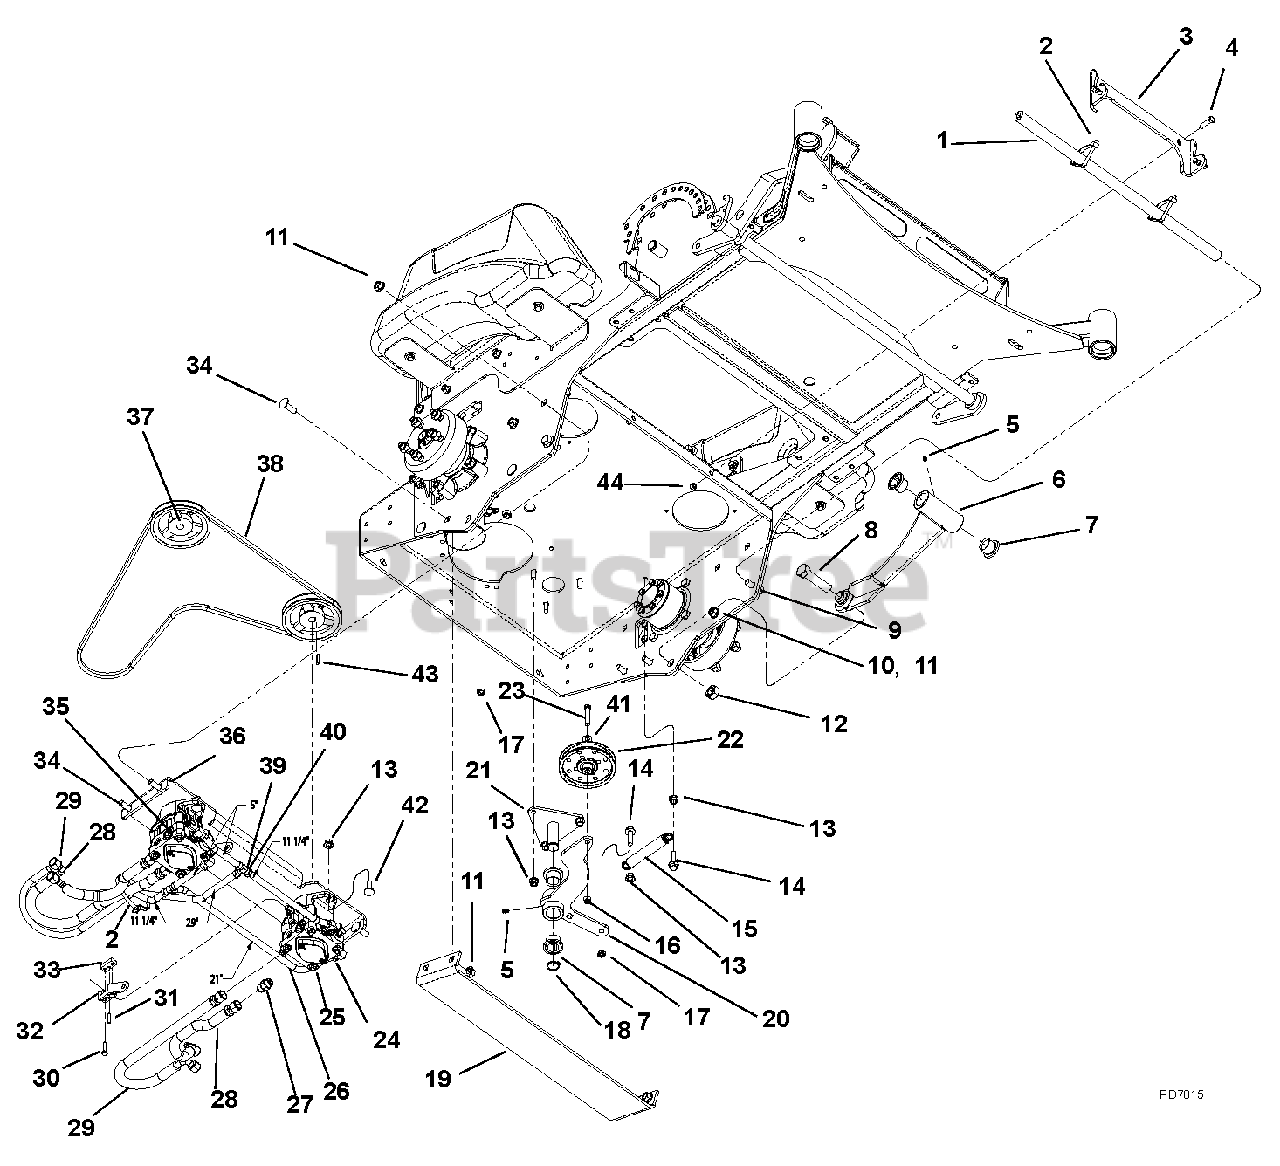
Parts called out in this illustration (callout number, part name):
1	BAR, TIE
2	CABLE TIE, .31 X 14.6 -BLACK
3	WLDT, DAMPNER BRACKET
4	SCREW, HEX FLANGE HEAD
5	FTG, 1/4-28 STRGT GREASE ZERK
6	WLDT, LH THRUST ARM
7	BRG, FLG 1.00 X 1.25 X 1.00
8	SCREW, HEX HEAD 3/4-16X3.00 Y
9	SCREW, FL, JDS123, M14 X 2.0 X 30-10.
10	BOLT, RD HD SQNECK JDS137M 12 X 1.
11	LOCKNUT, M12 X 1.75 DFLCTFLG 10Y
12	LOCKNUT, 3/4-16 CROWN C
12	2
13	LOCKNUT, FL, ISO7044, M10-1.50
14	SCREW, HEX, FL, JDS121, M10 X 1.5 X 40
15	SPRING, EXT .900 X .135 X 4.50 Y
16	NUT, 3/8-16 PTHN
16	1
17	NUT, JDS182, M10 X 1.5-04-ZN
18	RING, SNAP
19	PLATE, SUPPORT
20	WLDT, ARM IDLER
21	PIVOT, IDLER MOUNTING, WELDMENT
22	PULLEY, FLAT 4.50 X .375 W/BRG
23	BOLT, 3/8 X 2.00 A17D ZINC HEX
24	FTG, 90 9/16 MOR X 3/8 HOSE
25	PUMP, HYDRO BDP-10A-101
26	HOSE, 3/8 SAE30R7 FUEL & OIL
27	FITTING, STRAIGHT
30	SCREW, HEX HEAD 1/4-28 X 1 1/4
31	PIN, SPRING M5X30 Y
32	WLDT, LH PUMP ARM
33	PLATE, PUMP A'TCH
34	BOLT, RHSSN M12 X 1.75 X 35 JDS137
35	PUMP, HYDRO BDP-10A-203
36	SUPPORT, HYDRAULIC PUMP
37	ASSY, PUMP PULLEY W/ SET SCREW
38	DRIVE BELT
39	FTG, TUN 3/8 HOSE
40	CLAMP, HOSE - 1/2" PINCH
41	WASHER, .406 X .812 X .065
42	BOLT, RH, SQNECK, JDS137, M10 X 1.5
43	KEY, M5 X M5 X M30 RD
44	LOCKNUT, 3/8-16 NYLOC Y
